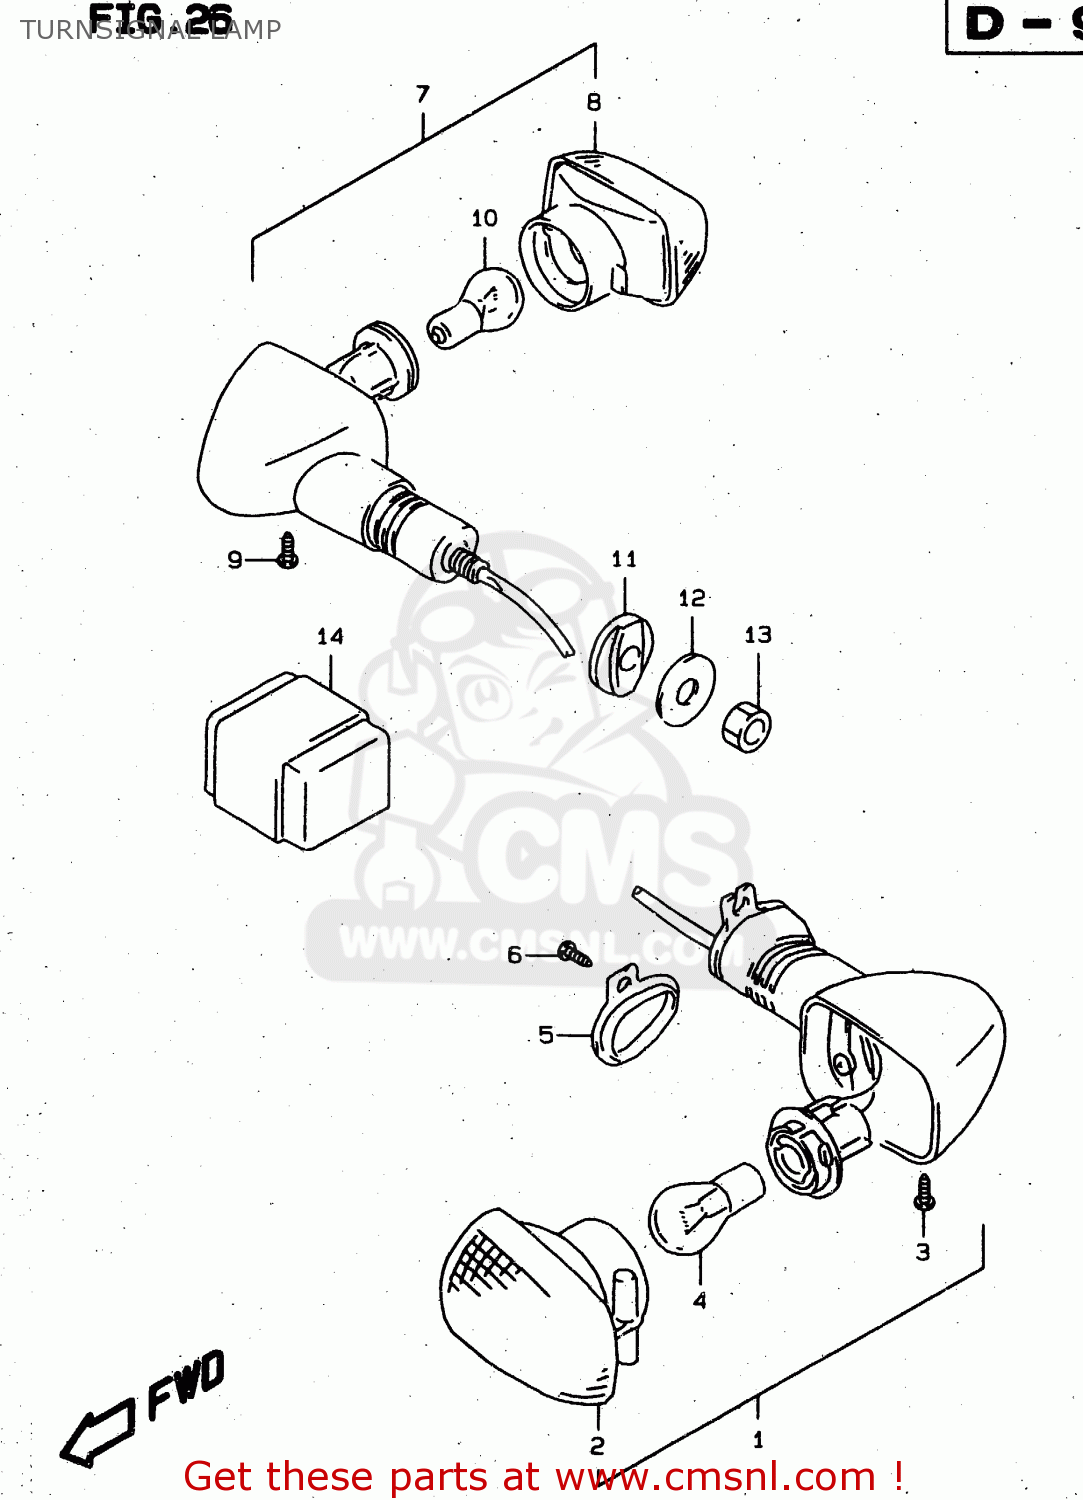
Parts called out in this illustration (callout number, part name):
1	LAMP ASSEMBLY,FRONT TURN SIGNAL
2	LAMP UNIT
3	SCREW
4	BULB(12V21W)
5	PLATE,FR TURNSIGNAL LAMP
6	SCREW
7	LAMP ASSY,RR TURNSIGNAL,R
8	LAMP UNIT
9	SCREW
10	BULB(12V21W)
11	SPACER,RR TURNSIGNAL
12	WASHER(10.5X30X2.3)
13	NUT
14	RELAY ASSY
